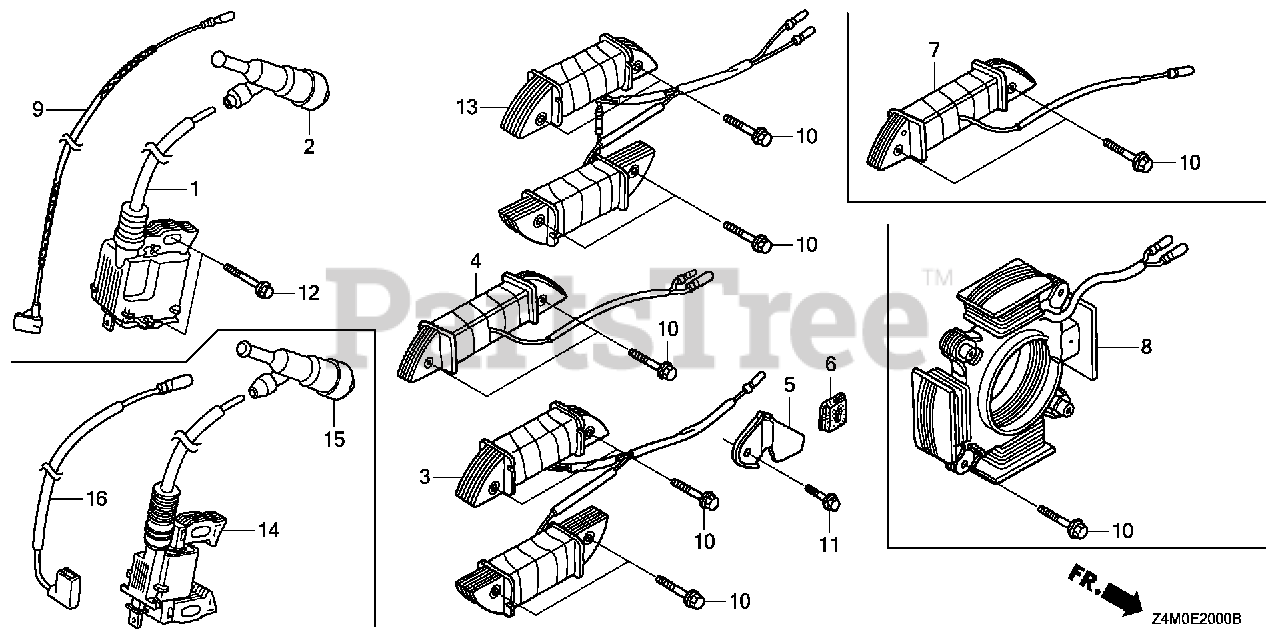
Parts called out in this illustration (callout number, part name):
1	COIL ASSY., IGNITION (TEC)
2	CAP ASSY., NOISE SUPPRESSOR (NGK)
2	CAP ASSY., NOISE SUPPRESSOR (TEC)
5	CLAMP, WIRE
6	GROMMET, WIRE
7	COIL ASSY., CHARGE (1A)
9	WIRE, STOP SWITCH (395MM)
10	BOLT, FLANGE (6X28) (CT200)
11	BOLT, FLANGE (5X10) (CT200)
12	BOLT, FLANGE (6X25) (CT200)
